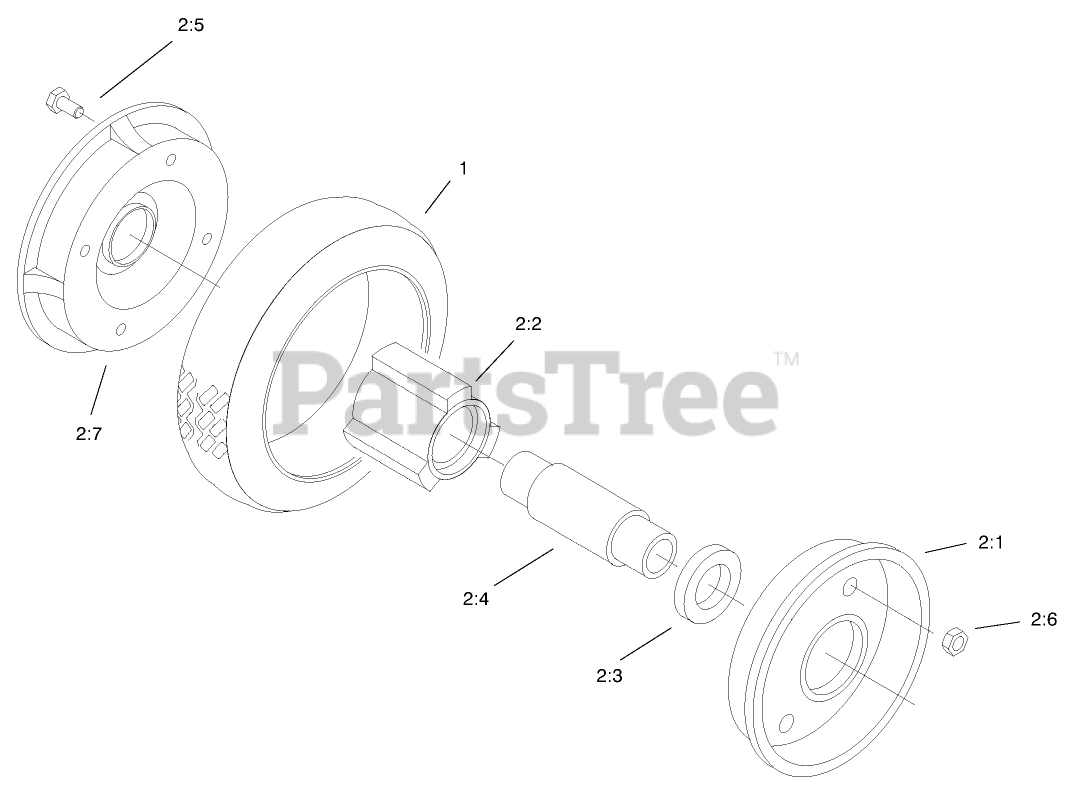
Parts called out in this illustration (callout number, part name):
2	Loose Parts Package
2:2	HUB-BEARING
2:3	BEARING-WHEEL
2:4	SPACER-BEARING
2:5	SCREW-HH
2:6	NUT-LOCK, NI
